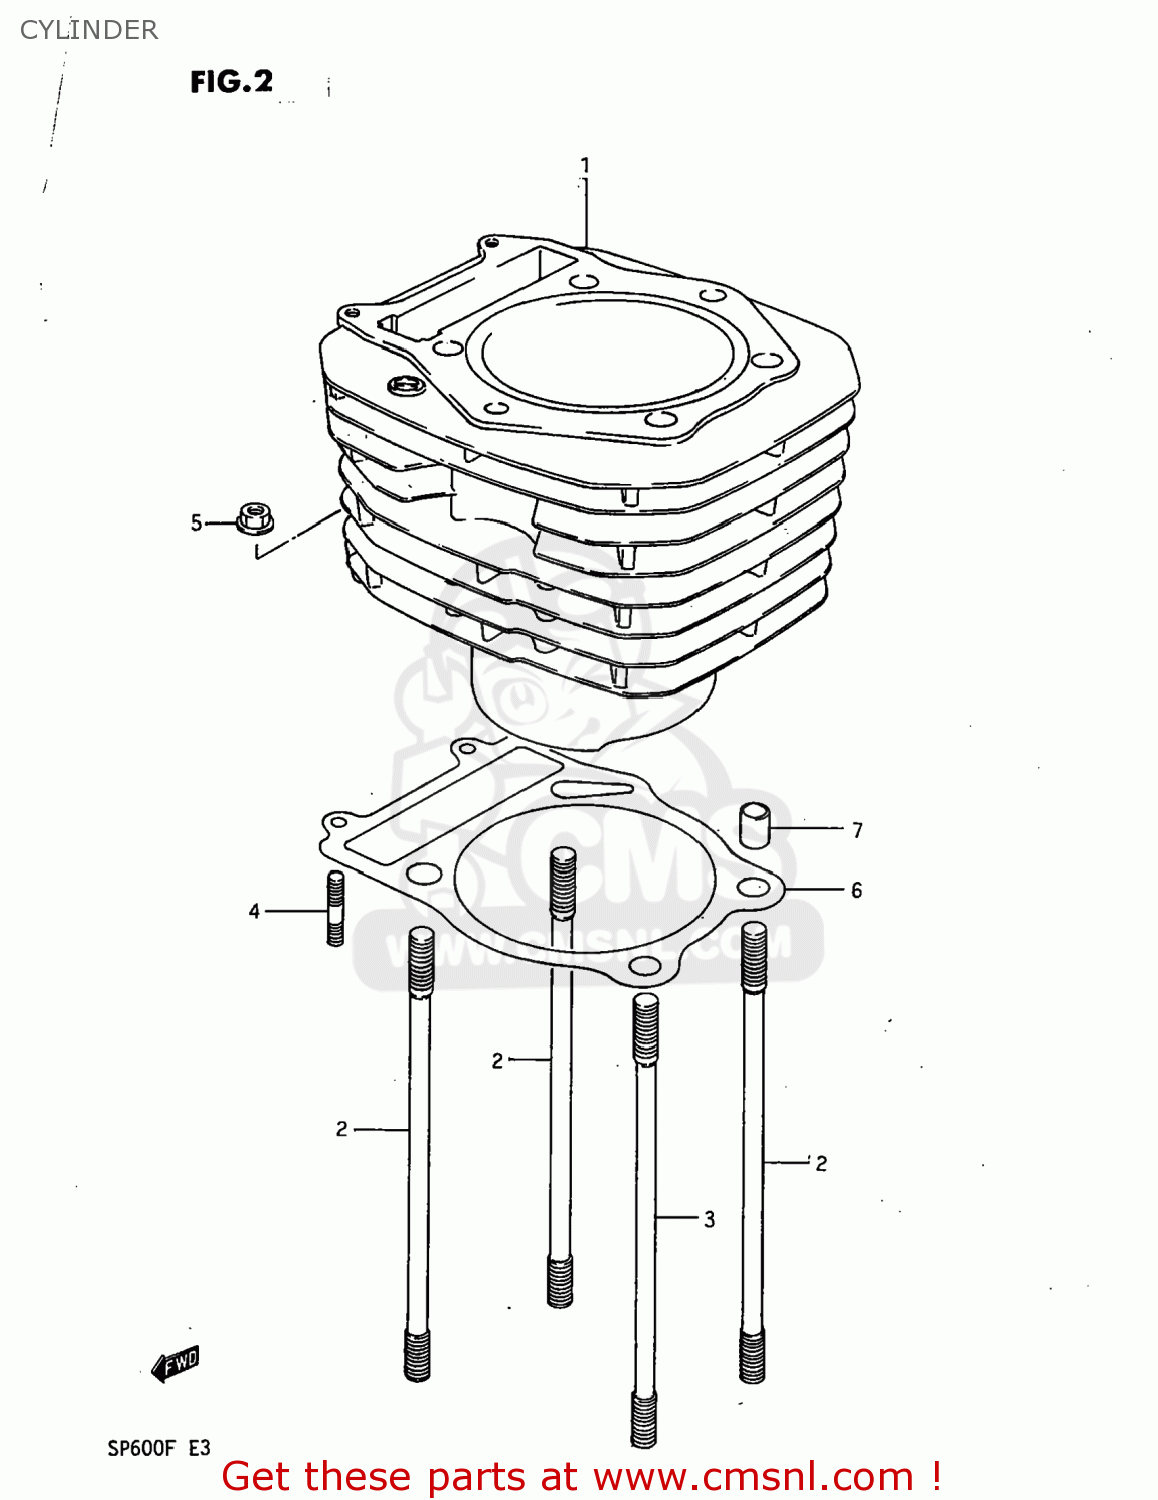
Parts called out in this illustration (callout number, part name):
1	CYLINDER
2	STUD
3	STUD
4	STUD BOLT L:20
5	NUT 6MM
6	GASKET,CYLINDER (MCA)
7	PIN
